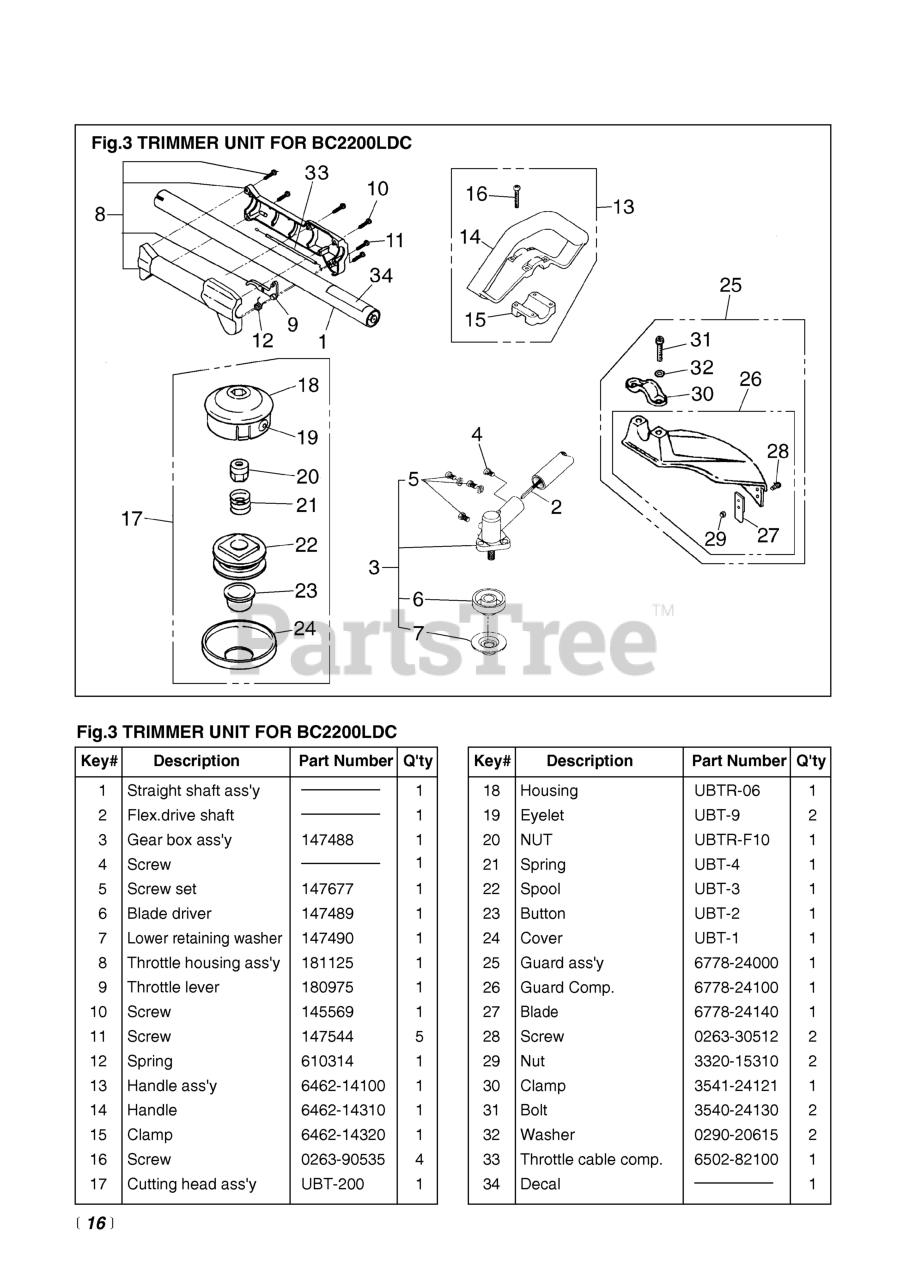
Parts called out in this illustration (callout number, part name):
1	STRAIGHT SHAFT ASSY
2	FLEX, DRIVE SHAFT
3	GEARCASE ASSEMBLY
4	SCREW
5	HARDWARE, MOUNTING
6	HOLDER (U), BLADE DRIVER
7	HOLDER (L) (RPLS 613222)
9	LEVER, THROTTLE
10	SET SCREW, ANTI-ROTATION
12	SPRING, THROTTLE TRIGGER
13	HANDLE ASSEMBLY
14	HANDLE
15	CLAMP
16	SCREW, M5 x 35
17	CUTTING HEAD ASSY
18	HOUSING (ROUND) (NLA)
19	EYELET
20	BOLT (10MM ROUND FEMALE)
21	SPRING
22	SPOOL
23	BUTTON
24	COVER
26	GUARD COMP
28	SCREW, M5 x 12
29	NUT
30	CLAMP
31	BOLT, M6 x 1.30
32	WASHER M6
33	CABLE COMP (RPLS 6460- )
34	DECAL
